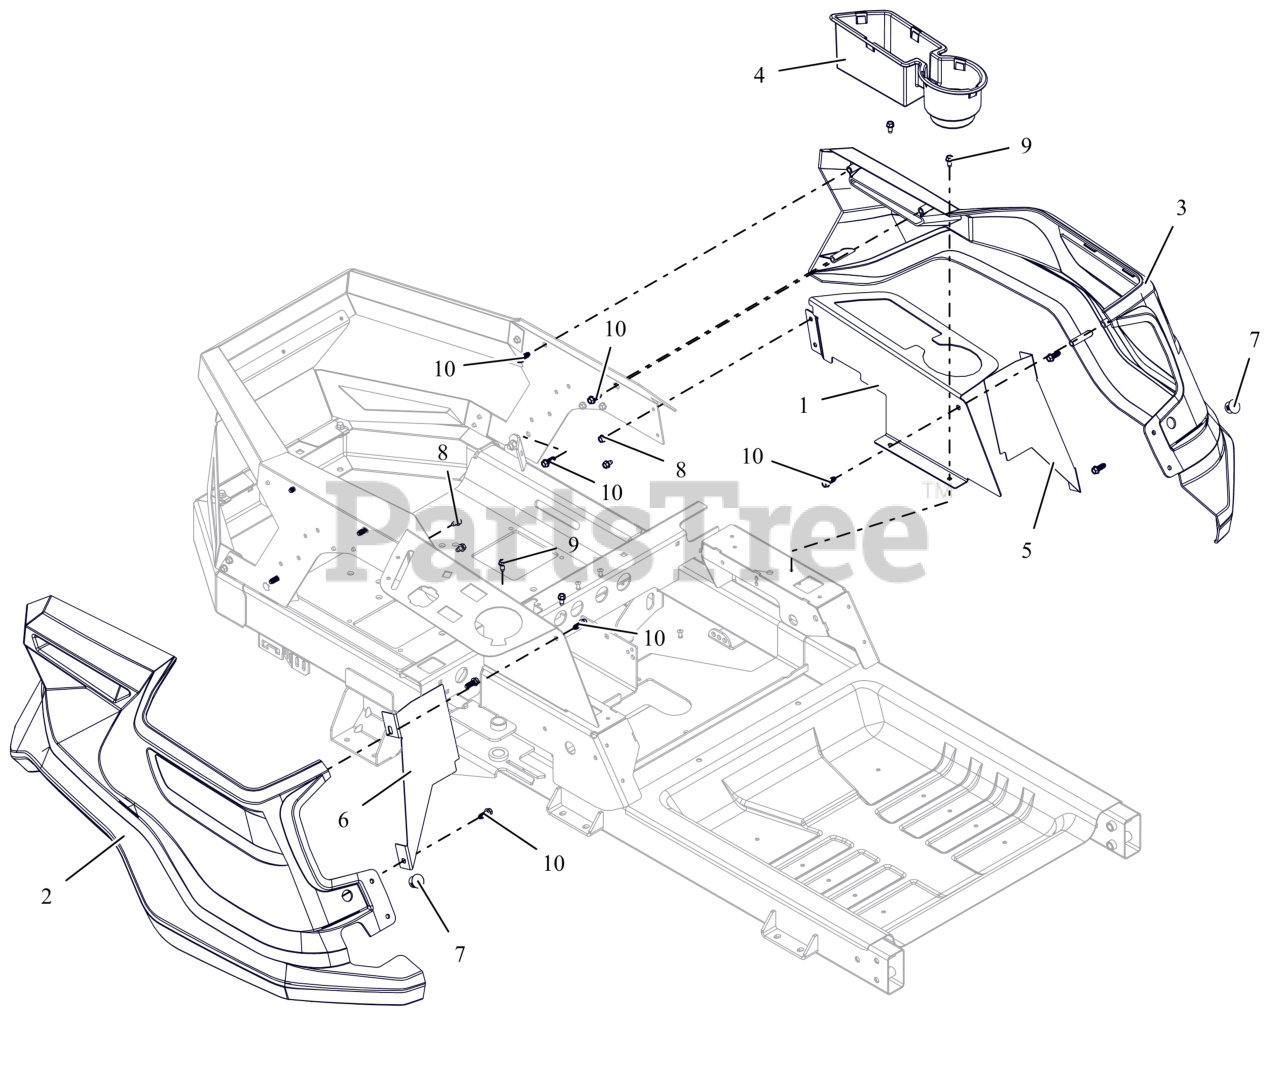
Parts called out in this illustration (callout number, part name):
1	PANEL, LEFT SIDE FENDER MOUNT
2	FENDER, RH IKON
3	FENDER, LH IKON
4	INSERT, CUP/STORAGE HOLDER
5	PLATE, LH BLOCKER
6	PLATE, RH BLOCKER
7	PLUG, HOLE .75 (BLACK)
8	SCR,TAP .25-20X.375 HWH TR ZCC
9	SCR-TAP .25-20X.50 HWH ZCC
10	SCR-.312X.75 #14H H/W/H H/L CZ
